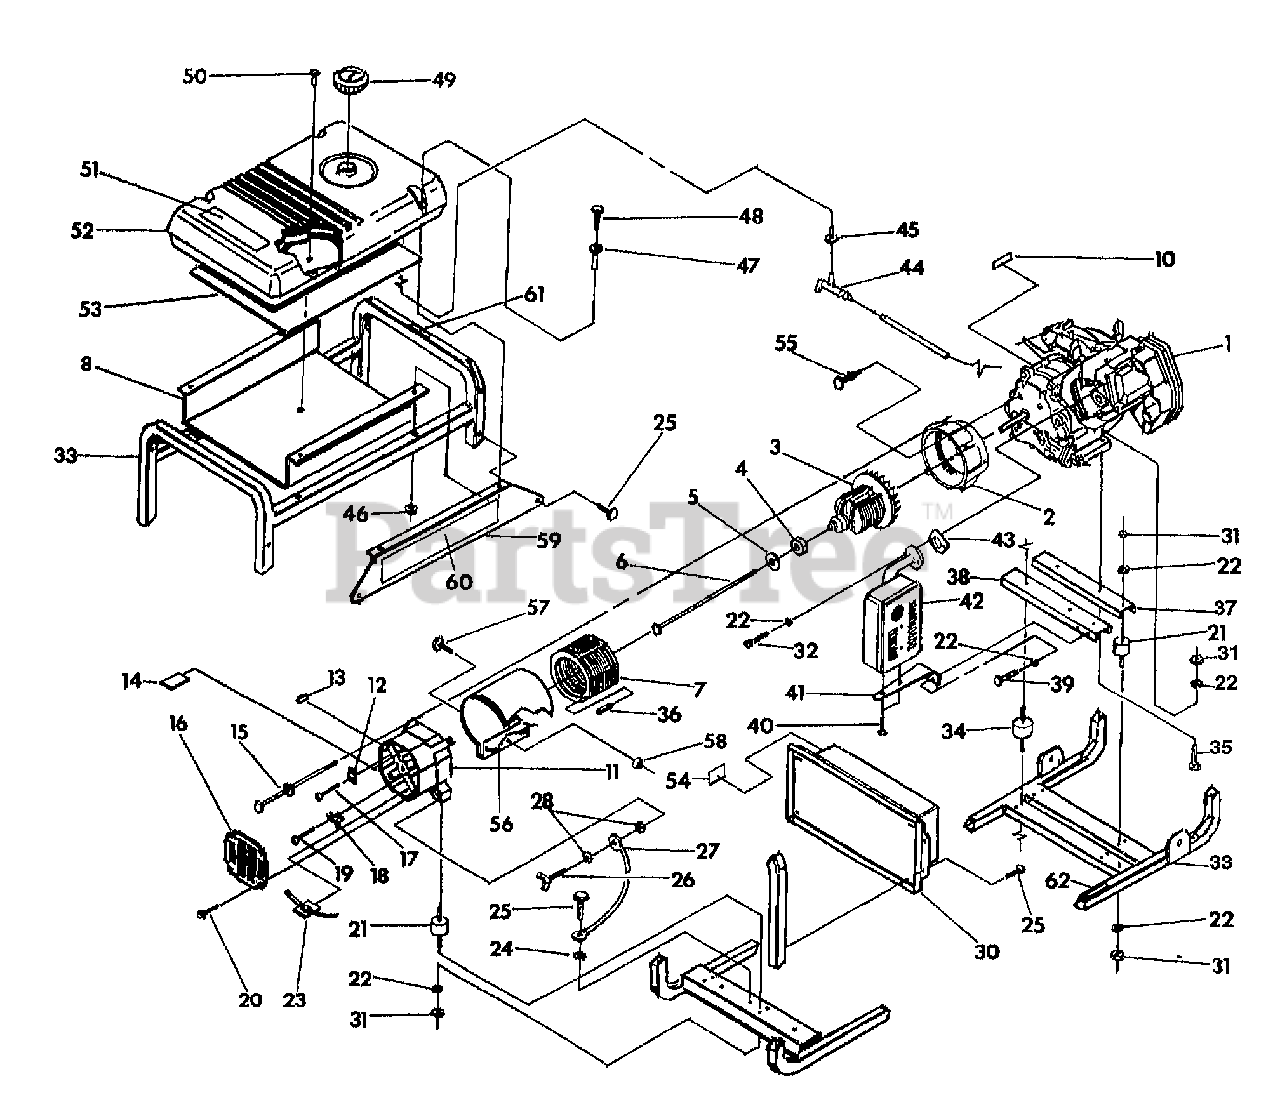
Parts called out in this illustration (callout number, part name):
1	ENG-GN360HS LONG BLOCK STR SHF
2	HSG-ENG ADAPTOR (6000W GEN)
3	ASSM-ROTOR (6000W GEN)
4	BEARING-SHAFT
5	WASHER-FLAT M8
6	SCR-HH 5/16-24X9.5
7	ASSM-STATOR (6000W GEN)
8	SHIELD-HEAT (6000W GEN)
10	DECAL-DATA (6000W GEN)
11	CARRIER-REAR BRG (6000W GEN)
12	RECTIFIER-BATTERY CHARGE (GEN)
13	GROMMET-RUBBER (4000/6000W GEN
14	MODULE-POWER (4000/6000W GEN)
15	SCR M6-1.0X165MM LG (6000W GEN
16	COVER-REAR BRG CARRIER
17	SCR-TAPTITE M5-0.8X20 LONG (GE
18	ASSM-BRUSH HOLDER (GENERATOR)
19	SCR-TAPTITE M5-0.7X16 LONG (GE
20	SCR-TAPTITE M5-0.8X10 LONG (GE
21	MOUNT-VIBRATION (6000W GEN)
22	WASHER-LK
23	MOUNT-CABLE TIE
24	WASHER-#10 SHAKEPROOF INT (600
25	SCR-CAP M10-16 SELF DRILL
26	SCR-WING M6-1.0X16 LONG (GEN)
27	WIRE-GROUND (GENERATOR)
28	WASHER-SHAKEPROOF M6 (GEN)
30	ASSM-CONTROL BOX (6000W GEN)
31	NUT-5/16X18 HEX (6000W GEN)
32	SCR-SKT HD M8-1.25X20 LONG (GE
33	CRADLE (6000W GENERATOR)
34	MOUNT-VIBRATION (6000W GEN)
35	SCR-HH 5/16-18X1.75
36	PIN-ROLL M4X10 (4000W GEN)
37	SUPT-ENGINE (6000W GEN)
38	SUPT-ENG & MUFFLER (6000W GEN)
39	SCR-HH 5/16-18X.75
40	SCR-HH/LW M6-1.00 12MM LG (GEN)
41	BRKT-MUFFLER (6000W GEN)
42	MUFFLER (6000W GENERATOR)
43	GASKET-MUFFLER (6000W GEN)
44	VALVE-TANK
45	BUSHING-PLASTIC TANK (PRS WSHR
46	NUT-HF/LK M6 FLANGE
47	GROMMET-TANK
48	SCR-HH M6-1.00X60MM LONG (GEN)
49	CAP-FUEL (6000W GENERATOR)
50	CLIP-INSULATION
51	DECAL-DANGER GENERATOR
52	TANK-FUEL (6000W GENERATOR)
53	INSULATION 2-1/4" THK (6000W G
55	SCR 5/16-24X.75 W/LK WSHR
56	WRAP-STATOR (6000W GEN)
57	SCR-HH M5-0.8X12MM
58	NUT-LK M5-.8
59	PANEL-SIDE (6000W GEN)
60	DECAL-TROY/BILT LOGO
61	DECAL-PLACE HAND HERE
62	DECAL-WARNING HOT SURFACE
